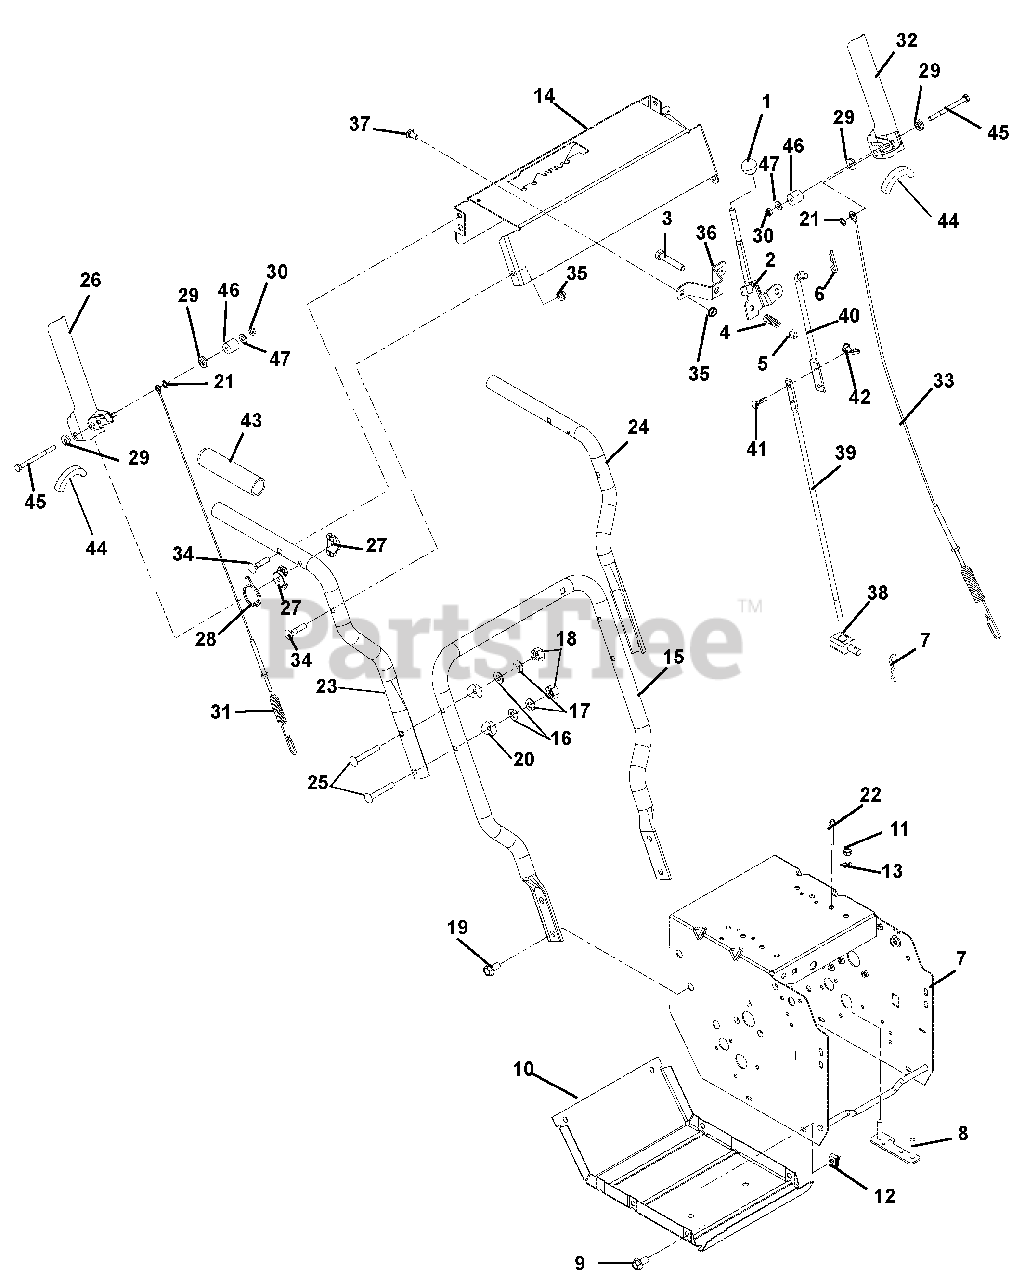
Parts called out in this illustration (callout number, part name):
1	Knob, Ball-Black 1.47, .375-16
2	Weldment, Shift Lever
3	Bolt, Hex .38-16 x 2.00 Grade 5
4	Spring, Compression
5	Nut, Locking Top Flange .38-16
6	Pin, Hair Internal .08 x .18 x 1.18
7	Weldment, Frame
8	Strap, Engine Bolt Weldment
9	Bolt, Hex Washer Head .25-20 x .75 Grade 5
10	Cover Bottom
11	Nut, Hex .31-18
12	Nut, Retainer .25-20 x .56
13	Washer, Locking .31 x .097 Heavy
14	Control Panel with Decals
15	Handlebar, Lower
16	Washer, Flat Steel .38 x .845 x .83
17	Washer, Locking .31 x .078 Regular
18	Nut, Locking Nylon .312-18
19	Bolt Serrated Hex Flange Washer Head .38-16 x .75 Grade 5
20	Spacer, Handlebar
21	Ring, Retaining, External .25 x .010
22	Rivet-Pop, .187
23	Handlebar, Upper RH
24	Handlebar, Upper LH
25	Bolt, Round Head Square Neck .31-18 x 2.25
26	Paddle, Clutch - RH
28	Spring, Torsion
29	Bushing, Flange
30	Nut, Jam Nylon .250-20 With Nylon Locking Type Insert
31	Cable, Attachment
32	Paddle, Clutch - LH
33	Cable, Traction
34	Bolt, Round Head Square Extra Long Neck .31-18 x 1.50 Grade 5
35	Nut, Locking Top Flange .31-18
36	Bracket, Shift Mount
37	Bolt, Round Head Square Short Neck .31-18 x .62
38	Pivot, Shift Rod
39	Rod, Shift Lower
40	Rod, Shift Upper
41	Bolt, Round Head Square Neck .25-20 x .75 Grade 5
42	Nut, Locking Top Flange .25-20
43	Handle Grip
44	Edging, Clutch Paddle 2.00"
45	Bolt, Hex .25-20 x 3.25
46	Bushing, Sleeve
47	Washer, Flat, Steel .281 x .62 x.065
